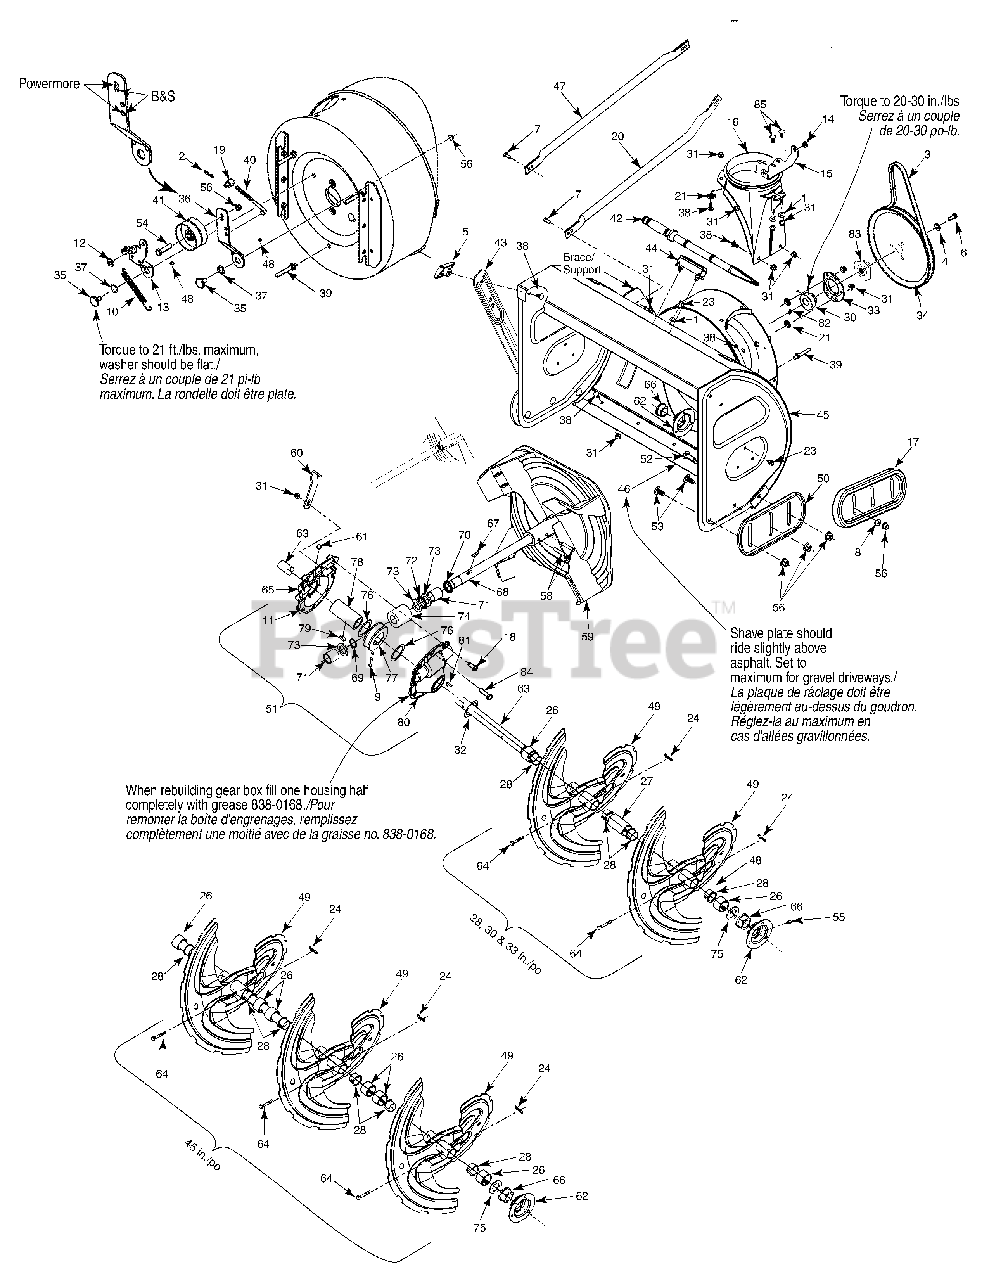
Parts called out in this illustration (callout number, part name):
1	Flat Washer .349 ID x .879 OD x .063
2	Int. Cotter Pin
3	V-Belt 1/2 x 44.60" Lg.
4	Flat Washer .34 x 1.5 x .150
5	Handle Knob Assembly
6	Hex Screw 5/16-24 x .875 Gr. 8 Lock
7	Hex Hd Cap Scr. 5/16-18 x .75 Gr. 5
8	Flat Washer .385 x .870 x .092
9	Shell Alvania Grease (3 oz.)
10	Extension Spring .470 Dia. x 4.75
11	Ultra Grey Loctite #5699
12	Flat Washer .344 ID x .75 OD x .120
13	Brake Bracket Ass’y (900 Series)
14	Plastic Bushing .380 ID
15	Chute Brkt.
16	Chute Adapter
18	Screw, 5/16-18 x .5
19	Adjustment Ferrule
21	Push-on Nut .25 dia.
23	Hex TT Screw 5/16-18 x .75
24	Bow Tie Cotter Pin
26	Spacer 1.5 x 1.0 ID x 1.0" Lg.
27	Spacer 1.5 x 1.0 ID x 2.5" Lg.
28	Flange Bushing 1.05 ID x 1.16 OD
30	Self-Aligning Bearing .875 ID
31	Hex Flg. L-Nut 5/16-18 Gr. F Nylon
32	Flat Washer 1.010 x 1.88 x .060
33	Bearing Housing
34	Pulley .5 ID x 10 OD
35	Shoulder Scr .625 Dia x .170
36	Auger Idler Bracket
37	Wave Washer .625 ID x .885 OD x .015
38	Carriage Bolt 5/16-18 x .75
39	Screw 5/16-18 x .43 (w/stud)
40	Auger Idler Rod
41	Flat Idler Pulley
42	Cleanout Tool
43	Drift Cutter
44	Cleanout Tool Mount
45	Snowthrower Housing Ass’y 28"
45	Snowthrower Housing Ass’y 30"
45	Snowthrower Housing Ass’y 33"
46	Shave Plate 28"
46	Shave Plate 30"
46	Shave Plate 33"
47	Support Tubing (w/steel panel)
48	Arctic Grease
49	Augers LH
49	Augers RH
50	Reversible Slide Shoe
51	Worm Gear Box Ass’y (w/ grease fitting)
52	Carriage Bolt 3/8-16 x 1.00" (w/steel shoe)
53	Carriage Bolt 3/8-16 x .75" (w/steel shoe)
54	Hex Hd. Cap Scr 3/8-16 x 1.75 Gr. 5
55	Grease fitting
56	Hex Flange L-Nut 3/8-16 Gr. F Nylon
58	Spring Spirol Pin Heavy - 5/16 dia x 1.7
59	Blower Fan Ass’y Complete
60	Gear Housing Support Bracket
61	Barbed Plug
62	Bearing Housing (w/grease fitting)
63	Auger Shaft - 28"
63	Auger Shaft - 30"
63	Auger Shaft - 33"
64	Shear Pin 5/16-18 x 1.75
65	Gear Housing Half - RH
66	Flange Bearing
67	#9 HI-Pro Key 3/16 x 3/4 Dia HT
68	Auger Drive Shaft
69	Snap Ring for .875 dia. shaft
70	Oil seal for .875 ID Garlock (76 x 6133)
71	Sleeve Bearing .875 ID
72	Thrust Bearing .88 ID x 1.44 OD x .078
73	Flat Washer .88 ID x 1.4 OD x .125
74	Worm Gear LH Double Thread
75	Spacer
76	Flat Washer 1.5 ID x 2.0 OD x .03
77	Worm Gear LH Dou ble Thread (Bronze)
78	Worm Gear Shaft
79	#91 Woodruff Key 1/4 x 3/4 Dia.
80	Gear Housing Half LH (w/grease fitting hole)
81	#91 Woodruff Key 1/4 x 3/4 Dia.
83	Pulley Adapter .75 Dia. w/pins
84	Hex Hd. Cap Scr. 5/16-18 x 1.0 Gr. 5
85	Carriage Bolt 5/16-18 x 1.00" Lg
